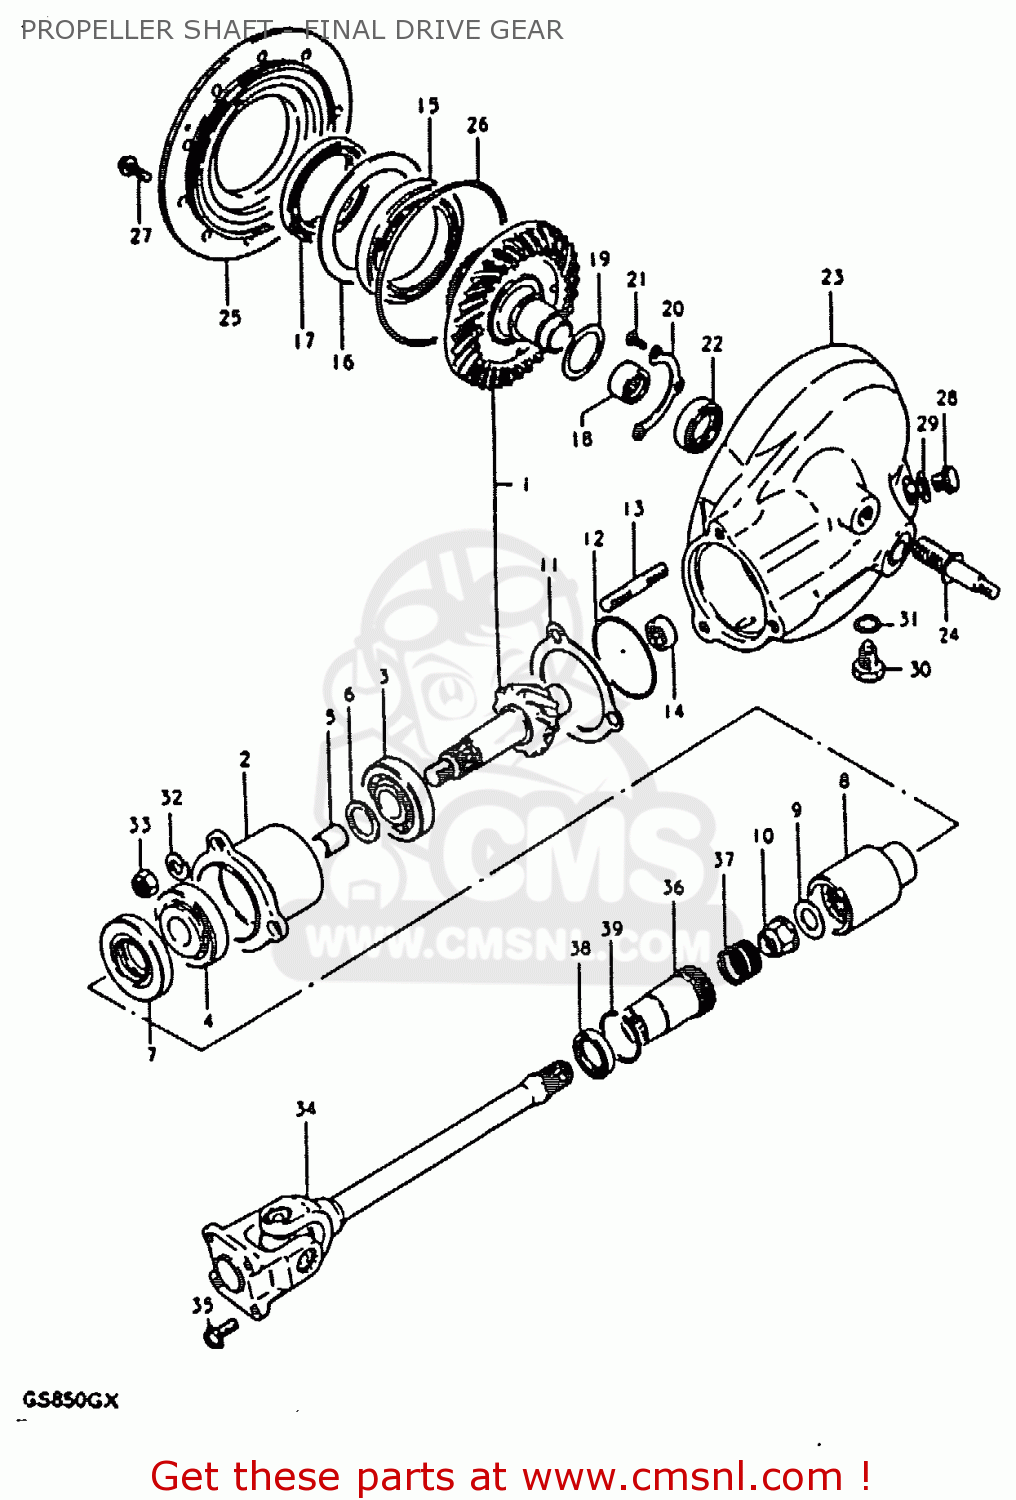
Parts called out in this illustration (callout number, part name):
1	GEAR SET,FINAL BEVEL
2	HOUSING,DRIVE GEAR
3	BEARING(25X52X19.25)
4	BEARING
5	SPACER (25.2X30X3.5)
6	SHIM (25X30X2
7	SEAL,OIL(32X54X7)
8	GEAR,FINAL DRIVE
9	WASHER(14X29X4)
10	NUT
11	SHIM,DRIVE GEAR HOUSING
12	O RING(D:2.4,ID:62.6)
13	STUD 10X30
14	BEARING(24X33X17)
15	BEARING(70X110X13)
16	SHIM,DRIVEN GEAR BEARING
17	SEAL,OIL(70X96X16)
18	BEARING(35X48X23.7)
19	SHIM,FINAL DRIVEN GEAR
20	RETAINER,FINAL DRIVEN GEAR BRG
21	SCREW 6X12
22	SEAL,OIL(30X42X7)
23	CASE ASSEMBLY,FINAL GEAR
24	STUD
25	CASE,FINAL GEAR BEARING
26	O-RING (D:3.1 ID:144.4)
27	BOLT
28	PLUG (14X12)
29	GASKET(14X19.2X2) (NAS)
30	PLUG
31	GASKET(14X19.2X2) (NAS)
32	LOCK WASHER
33	NUT
34	SHAFT ASSEMBLY,PROPELLER
35	BOLT 8X16
36	COUPLING,PROPELLER SHAFT
37	SPRING
38	SEAL,OIL(30X40.5X5.5)
39	CIRCLIP
